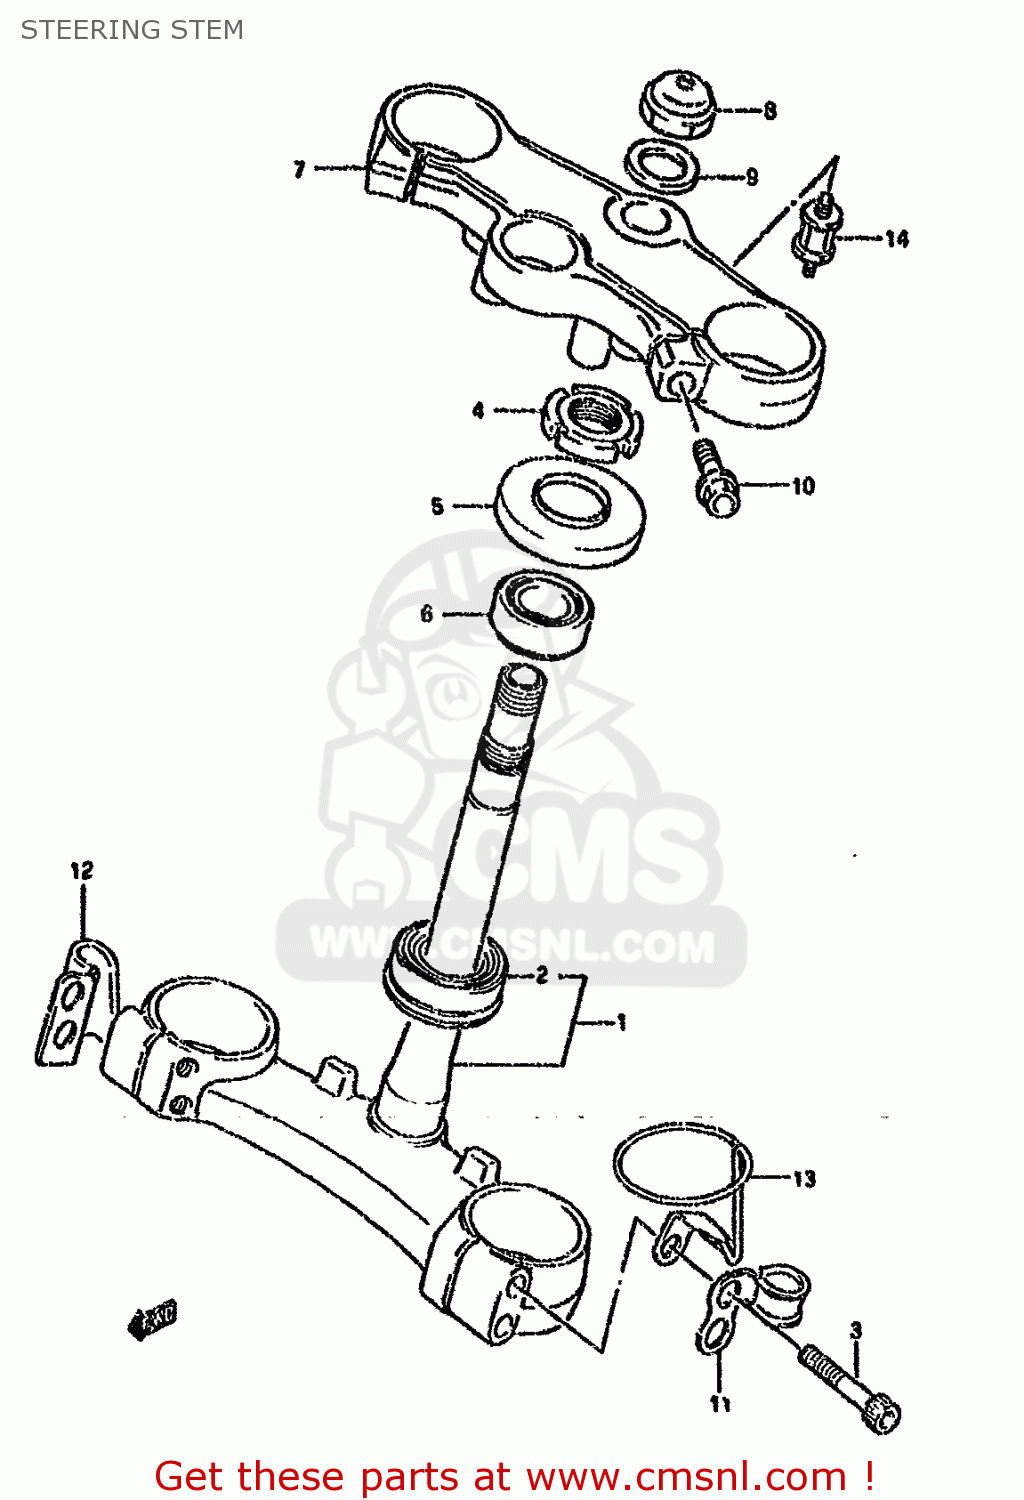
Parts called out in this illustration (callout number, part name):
1	STEM,STEERING
2	BEARING(30X55X17)
3	BOLT
4	NUT,STEERING STEM(25X44X10)
5	SEAL,OIL(34X69X11.9)
6	TAPER,ROLLER BEARING
7	HEAD,STEERING STEM
8	NUT
9	WASHER
10	BOLT
11	GUIDE,SPEEDOMETER CABLE
12	CLAMP,CLUTCH CABLE
13	HOLDER,STEERING DAMPER
14	BOLT,SPEEDOMETER CUSHION
